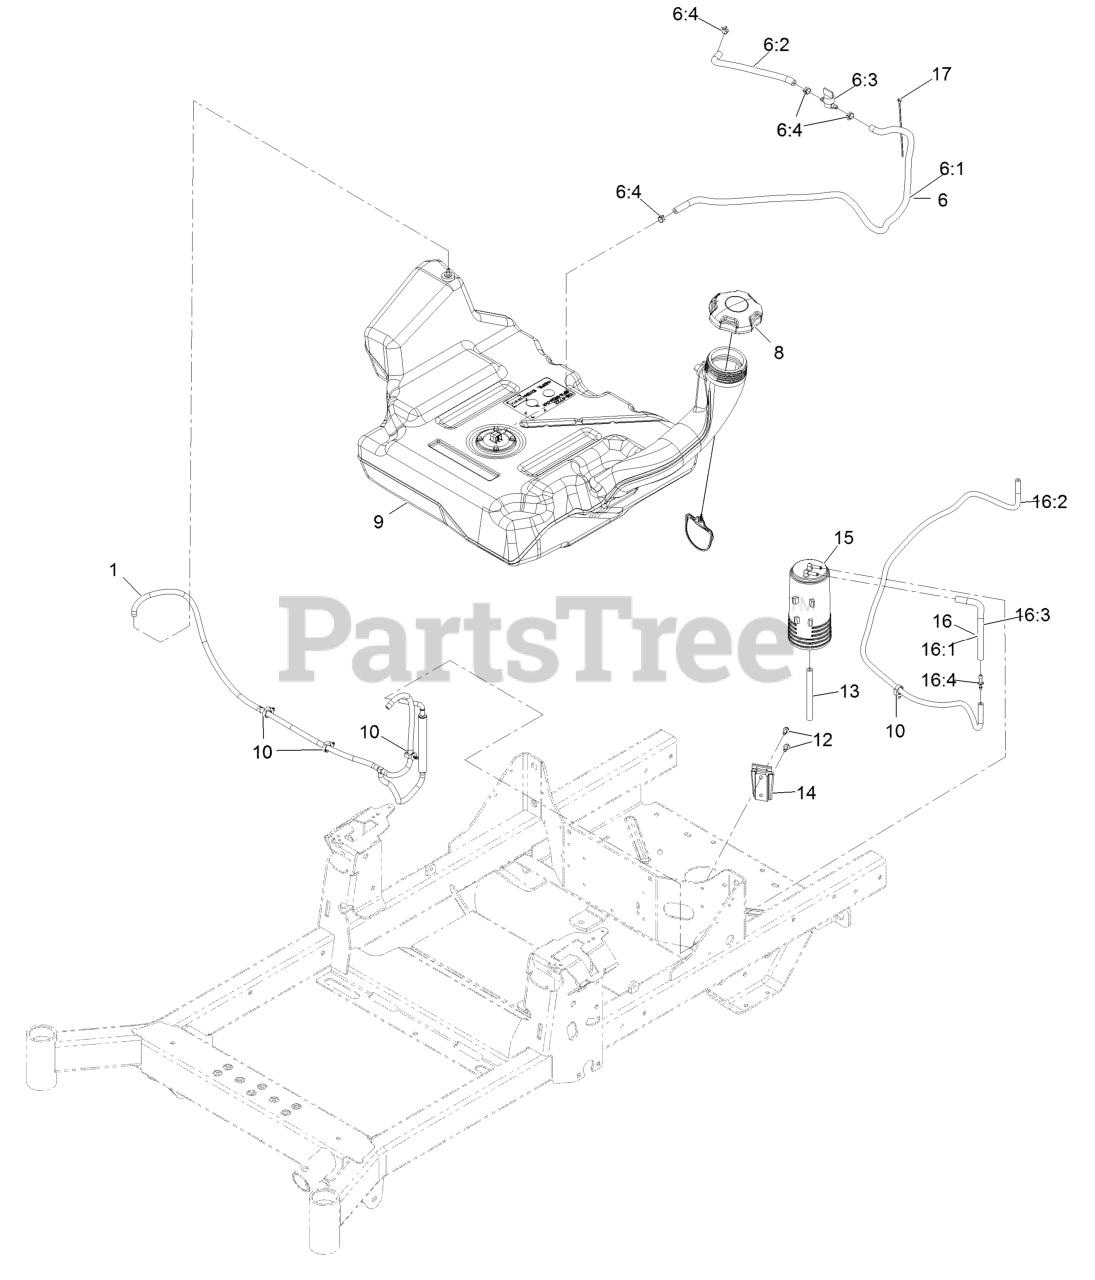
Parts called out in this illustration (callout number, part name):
1	VENT HOSE ASM
6	FUEL HOSE ASM
6:1	HOSE-FUEL
6:2	HOSE-FUEL
6:3	VALVE-FUEL
6:4	CLAMP-HOSE
9	TANK-FUEL
12	SCREW-HWH
13	HOSE-FUEL
14	BRACKET-CANISTER, CARBON
15	CANISTER-CARBON, 800CC
16	VENT HOSE ASM
16:1	HOSE-FUEL
16:2	HOSE-FUEL
16:3	CARTRIDGE-VALVE, CHECK
16:4	FITTING-STRAIGHT
17	TIE-CABLE
